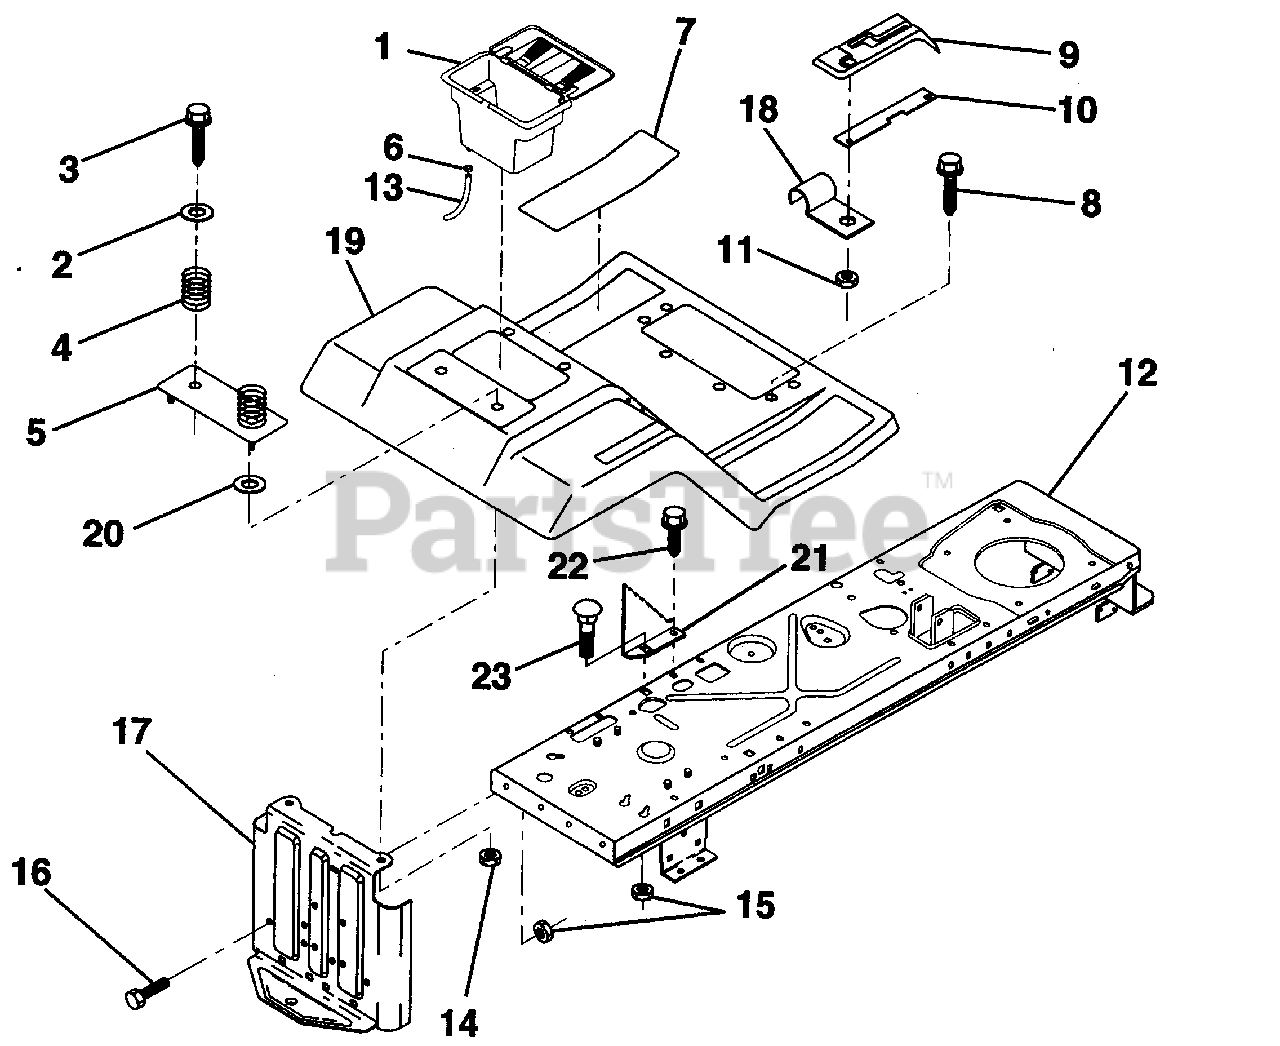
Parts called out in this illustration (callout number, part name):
1	Case, Battery (AYP part number)
2	Washer 13/32 x 1-1/4 x 12 Gauge (AYP part number)
3	Screw, Hex Washer Head, Thd. Roll. 3/8-16 x 3/4 (AYP part number)
4	Spring, Compression, Seat (AYP part number)
5	Plate, Fender (AYP part number)
6	Clamp, Hose (AYP part number)
7	Pad, Footrest (AYP part number)
8	Screw, Hex Washer Head, Thd. Roll. 5/16-18 x 3/4
9	Console, Shift Control (AYP part number)
10	Bar, Shift Lock (AYP part number)
11	Nut, Self-Threading 3/16 (AYP part number)
12	Assembly, Frame (AYP part number)
13	Tube, Battery Drain (AYP part number)
14	Nut, Hex, Keps 1/4-20 (AYP part number)
15	Nut, Crownlock 5/16-18
16	Bolt, Hex 5/16-18 UNC x 3/4 (AYP part number)
17	Drawbar (AYP part number)
18	Clip, Insulated (AYP part number)
19	Fender/Footrest (AYP part number)
20	Washer 9/32 x 7/8 x 13 Gauge (AYP part number)
21	Plate, Depth Stop (AYP part number)
22	Screw, Thd. Roll. 5/16-18 x 1/2 (AYP part number)
23	Bolt, Carriage 5/16-18 x 3/4 (AYP part number)
